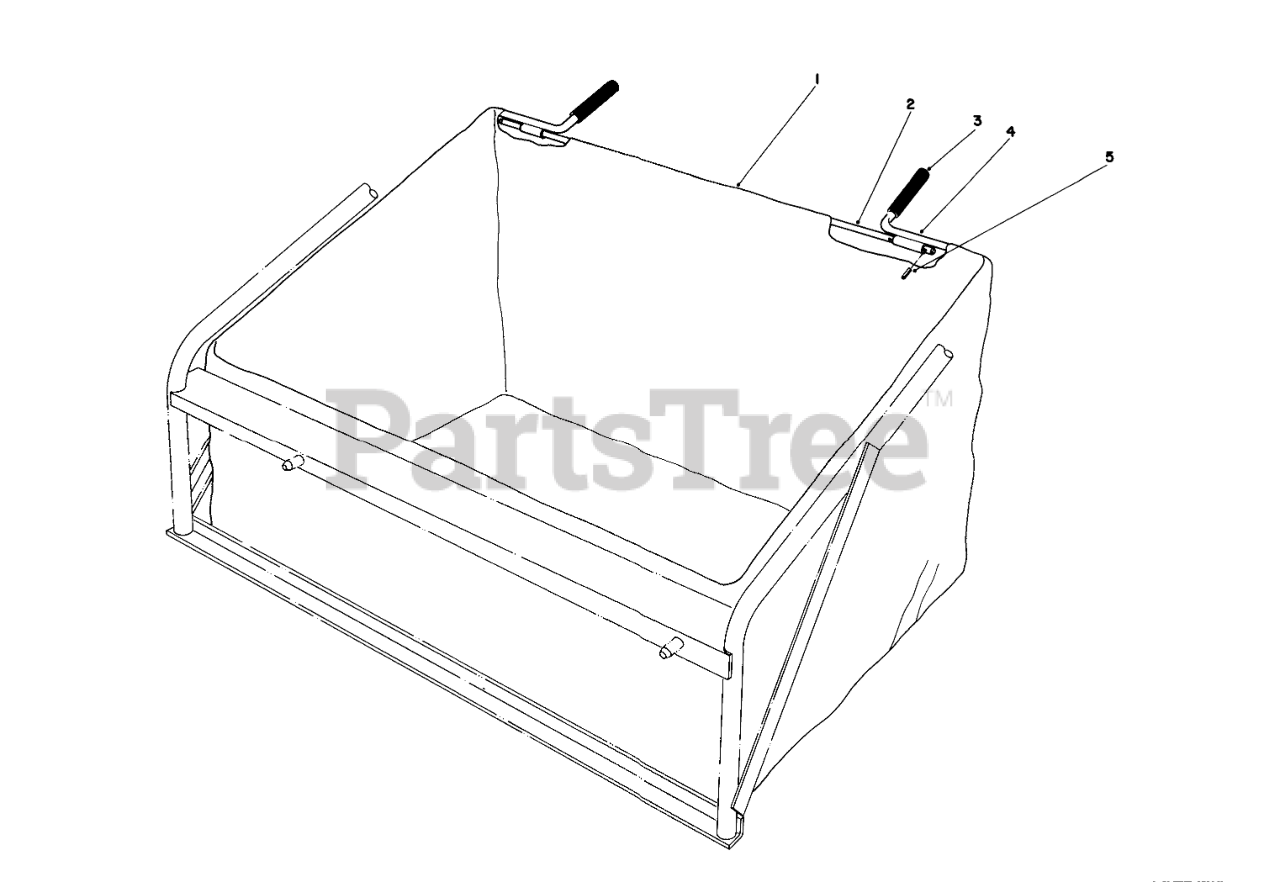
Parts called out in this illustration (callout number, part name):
1	Bag-Leaf Catcher
2	BAG FRAME ROD
3	BAG HANDLE GRIP
4	BAG FRAME WA B
5	PIN-ROLL
